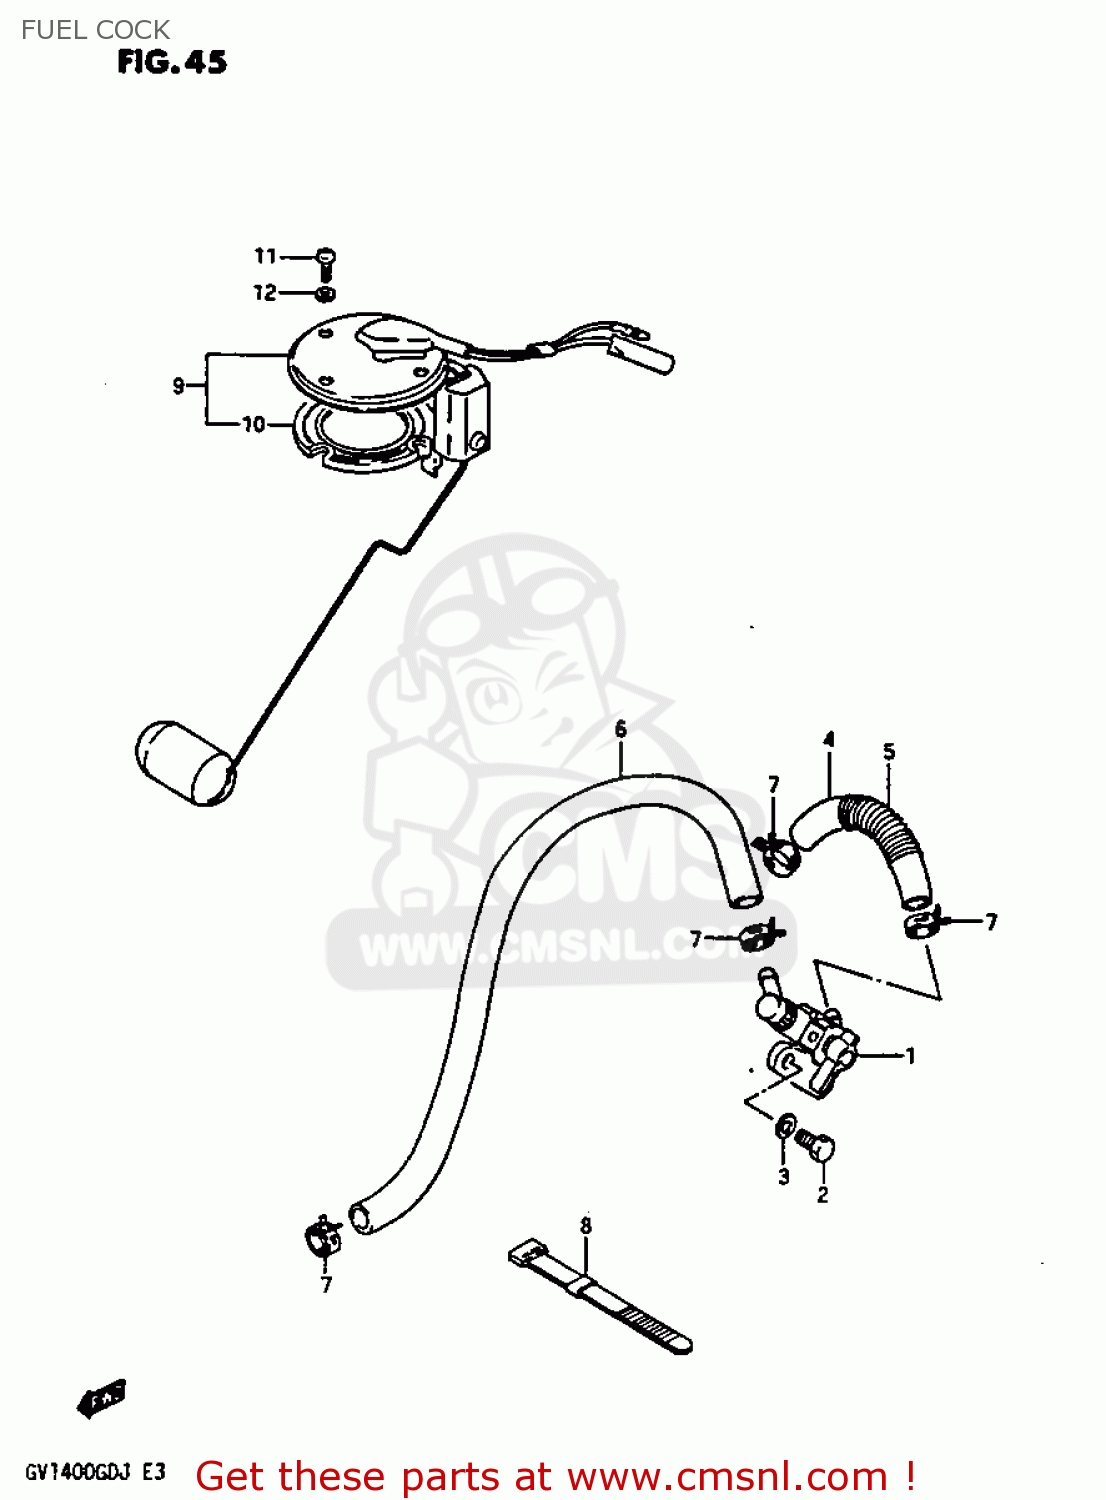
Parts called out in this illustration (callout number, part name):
1	COCK ASSEMBLY,FUEL
2	BOLT
3	WASHER,LOCK
4	HOSE
5	SPRING
6	HOSE
7	CLIP
8	CLAMP(L:187)
9	GAUGE ASSEMBLY,FUEL LEVEL
10	GASKET (NAS)
11	BOLT
12	LOCK WASHER
